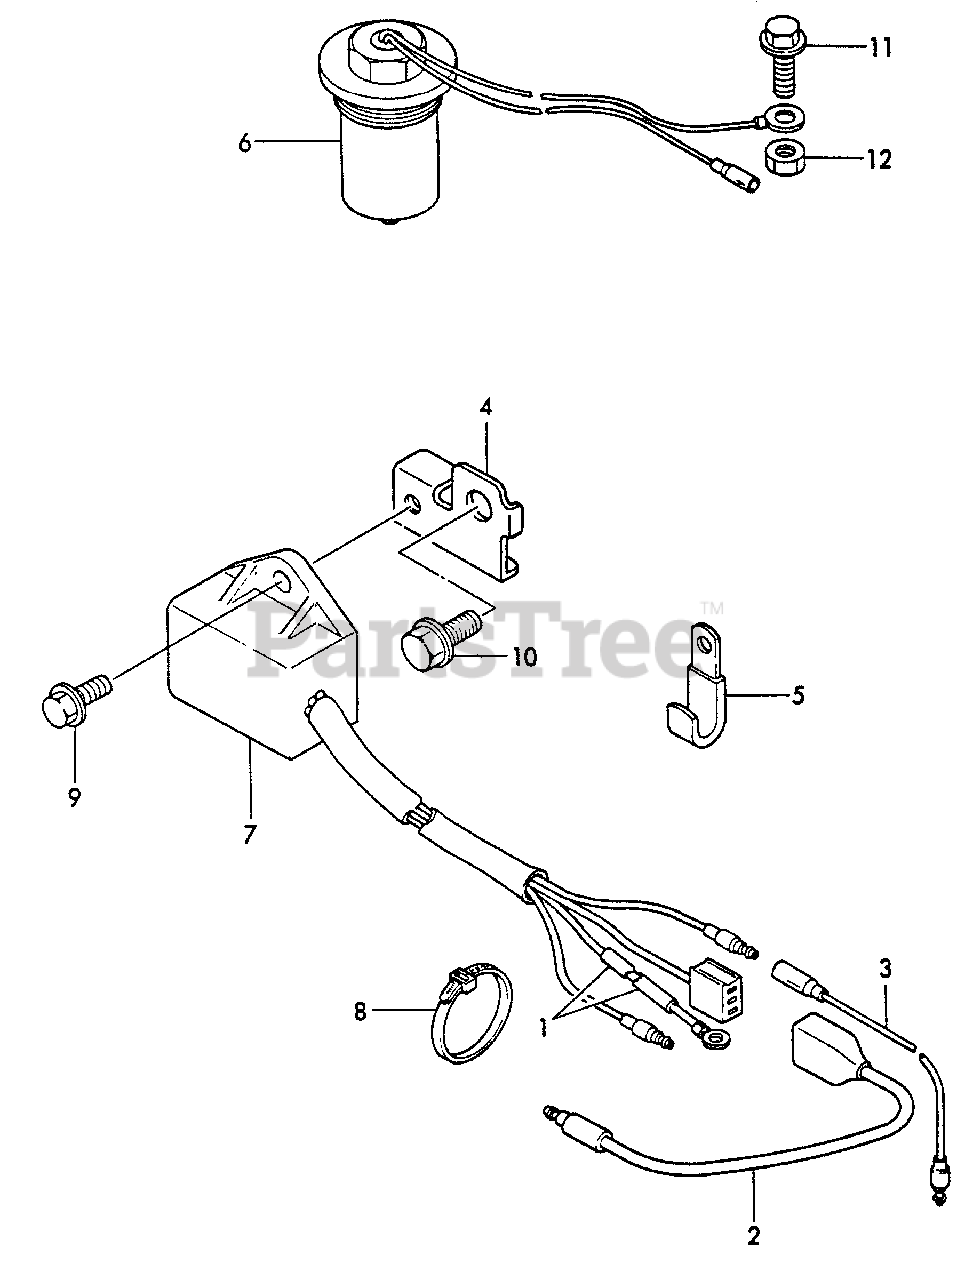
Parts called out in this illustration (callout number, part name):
1	TUBE, INSULATOR
2	WIRE
3	WIRE, SENSOR UNIT
4	STAY, SENSOR UNIT
5	CLAMP
6	SENSOR, OIL LEVEL
7	SENSOR, OIL
8	CLAMP
9	BOLT - 6X12 -- PLATED
10	BOLT - 8X14 -- PLATED
11	BOLT - 6X16 -- PLATED
12	LOCKNUT - 6 -- PLATED
